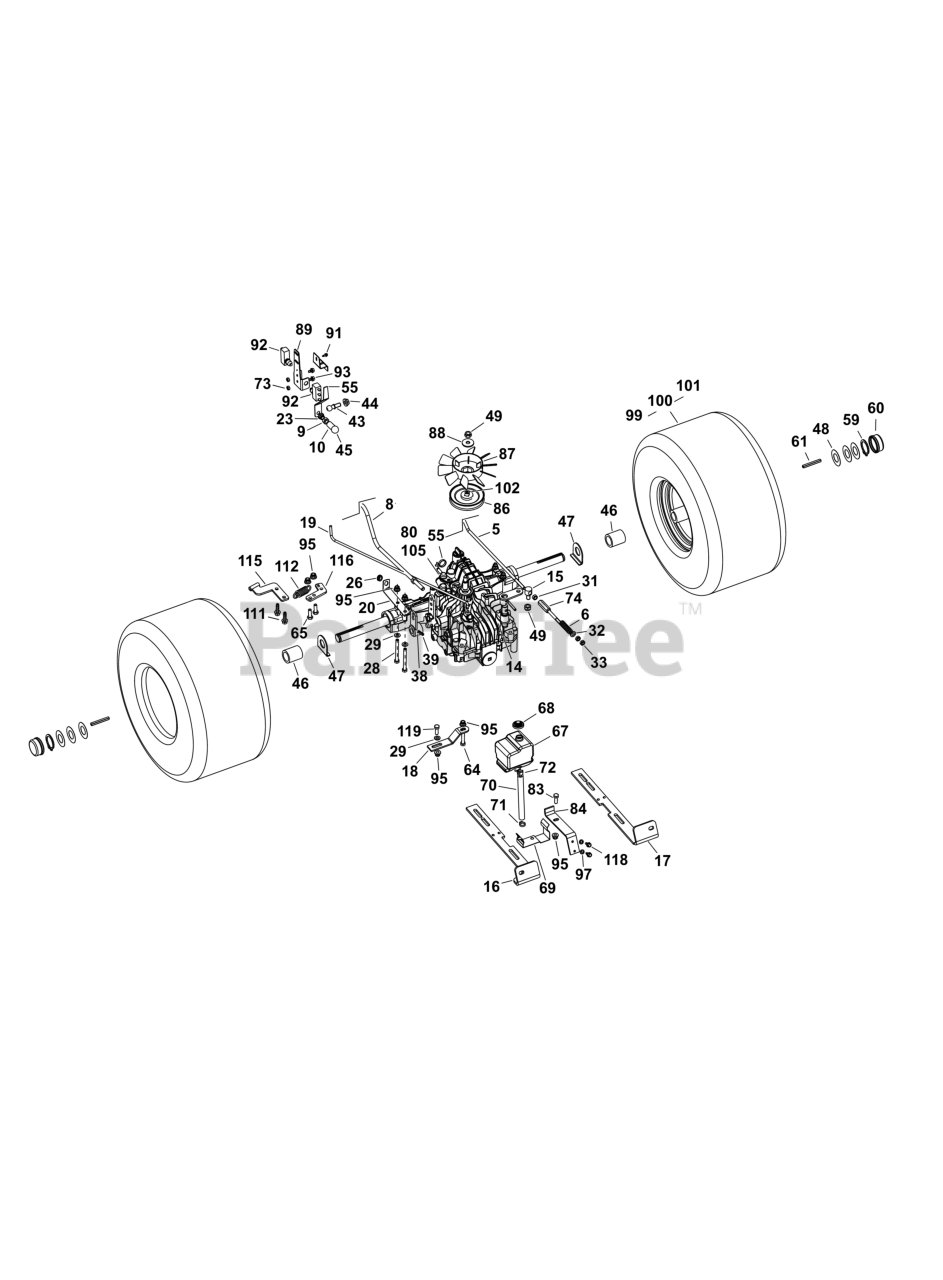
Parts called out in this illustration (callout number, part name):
5	ROD, Brake
10	JOINT, Ball
14	TRANSMISSION
16	PLATE, Left
17	PLATE, Right
43	JOINT, Ball
45	JOINT, Ball
59	RING, Locking
67	TANK, Oil
80	CONNECTOR
84	BRACKET, Support
92	MICROSWITCH
99	WHEEL, Rear
116	FOOT, Mounting
